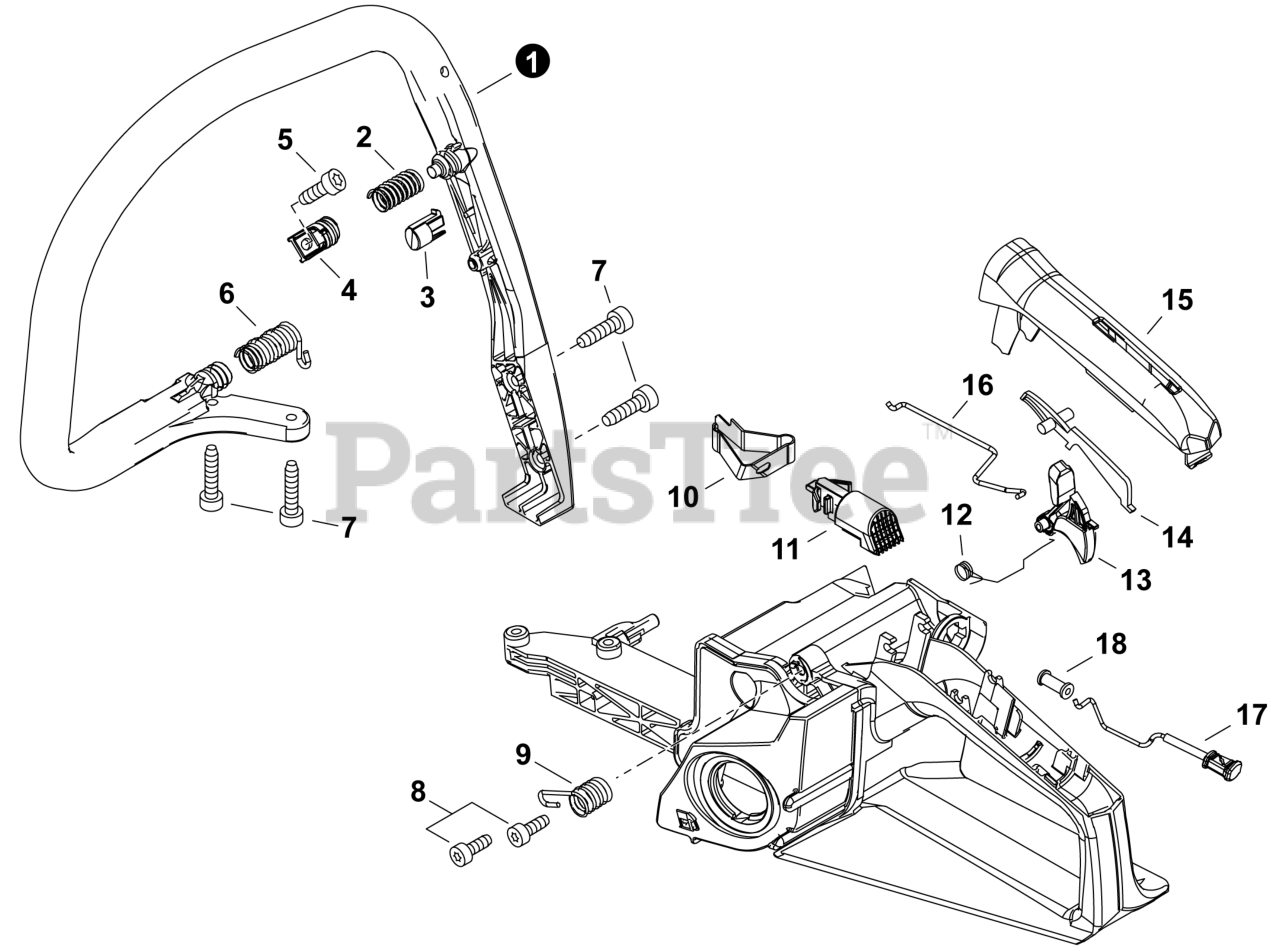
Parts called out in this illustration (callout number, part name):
1	HANDLE, FRONT
2	SPRING, COMPRESSION
3	CUSHION
4	HOLDER, SPRING
5	BOLT, TORX 5x12
6	SPRING, COMPRESSION
7	BOLT, TORX 5x20
8	BOLT, TORX 5x12
9	SPRING, COMPRESSION
10	TERMINAL, LEAD
11	SWITCH, STOP
12	SPRING, TORSION
13	TRIGGER, THROTTLE
14	LEVER, THROTTLE LOCKOUT
15	COVER, HANDLE
16	ROD, THROTTLE
17	KNOB, CHOKE
18	GROMMET, CHOKE
